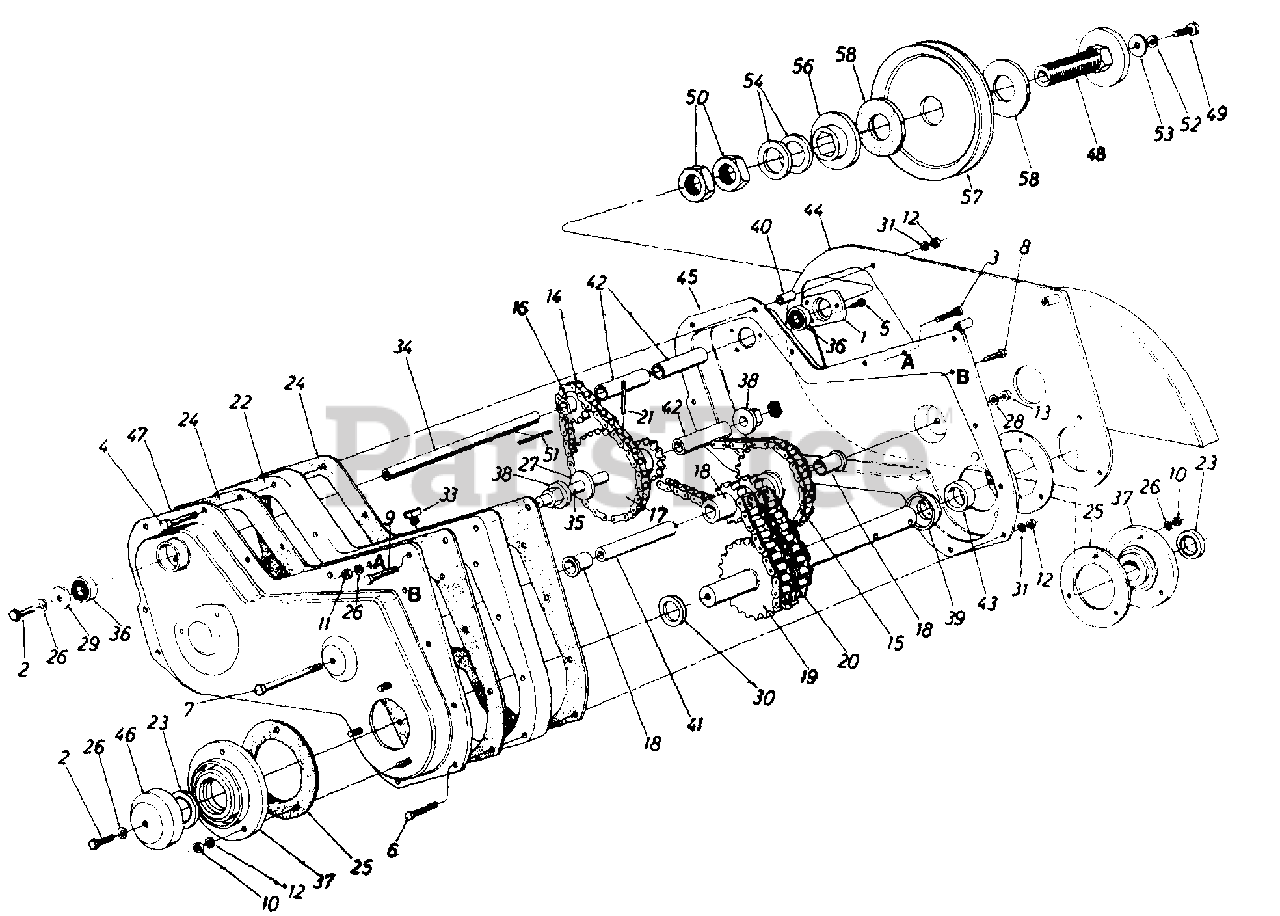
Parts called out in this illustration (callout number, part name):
1	Bearing Housing 1-3/8" Dia.
2	Hex Bolt 5/16-18 x .88" (Spec.)
3	Hex Bolt 5/16-18 x 1.5" Lg.
4	Hex Bolt 1/4-20 x 2.75" Lg.
5	Hex S-Tap Scr. 1/4-20 x .5" Lg.
6	Hex Bolt 1/4-20 x 1.5" Lg.
7	Hex Bolt 3/8-16 x 4.5" Lg.
8	Hex Scr. 1/4-20 x 1.5" Lg.
9	Hex TT-Tap Scr. 5/16-18 x 1.75"
10	Hex L-Nut 5/16-18 Thd.
11	Hex Nut 5/16-18 Thd.
12	Hex Nut 1/4-20 Thd.
13	Hex Nut 3/8-16 Thd.
14	#41 Chain 1/2" Pitch x 34 Links - Endless
15	#42 Chain 1/2" Pitch x 48 Links - Endless
16	Sprocket 10 Tooth .5" Pitch
17	10 & 28 Teeth Sprocket Ass'y.
18	8-2 & 28 Sprocket Sleeve Ass'y.
19	18-2 Sprocket Shaft Ass'y.
20	#50-2 Chain 5/8" Pitch x 28 Links - Endless
21	Spring Pin Spir. 1/4" Dia. x 1.5" Lg.
22	Spacer Block - Tiller Housing
23	Oil Seal 1-1/4" Dia.
24	Gasket for Tiller Housing
25	Gasket for Brg. Housing
26	L-Wash. 5/16" I.D.
27	Fl-Wash. .64" I.D. x 1.24" O.D.
28	L-Wash. 3/8" I.D. - H.D.
29	Fl-Wash. .344" I.D. x 1.125"
30	Special Washer
31	L-Wash. 1/4" I.D.
33	Vent Plug
34	Jack Shaft .525" I.D. x 7.78"
35	Sprocket Shaft .63" Dia. x 5"
36	Ball Brg. .62" I.D. x 1.38" O.D.
37	Bearing Housing - 1-1/4"
38	Hex Flange Brg.
39	Spacer 1.25" I.D. x 2.0" O.D.
40	Spacer .9" Lg.
41	Spacer 3.44" Lg.
42	Spacer .62" x .88 O.D. x 1.56" Lg.
43	Spacer .5" Lg.
46	Dust Cap
49	Hex Bolt 5/16-18 x 1.25" Lg. Grade 5
50	Hex Jam Nut 1.0-14 x 28 Thd.
51	Sq. Key 3/16 x 1.5" Lg.
52	L-Wash. 5/16" I.D.
53	Fl-Wash. .344" I.D. x 1.125"
54	Bell-Wash. 1.0" I.D. x 2.0"
56	Floating Disc 3-1/4" O.D.
57	5/8 V-Pulley 1.5" I.D. x 6.5"
58	Friction Pad 3-1/4" O.D. x 1-3/8" I.D.
